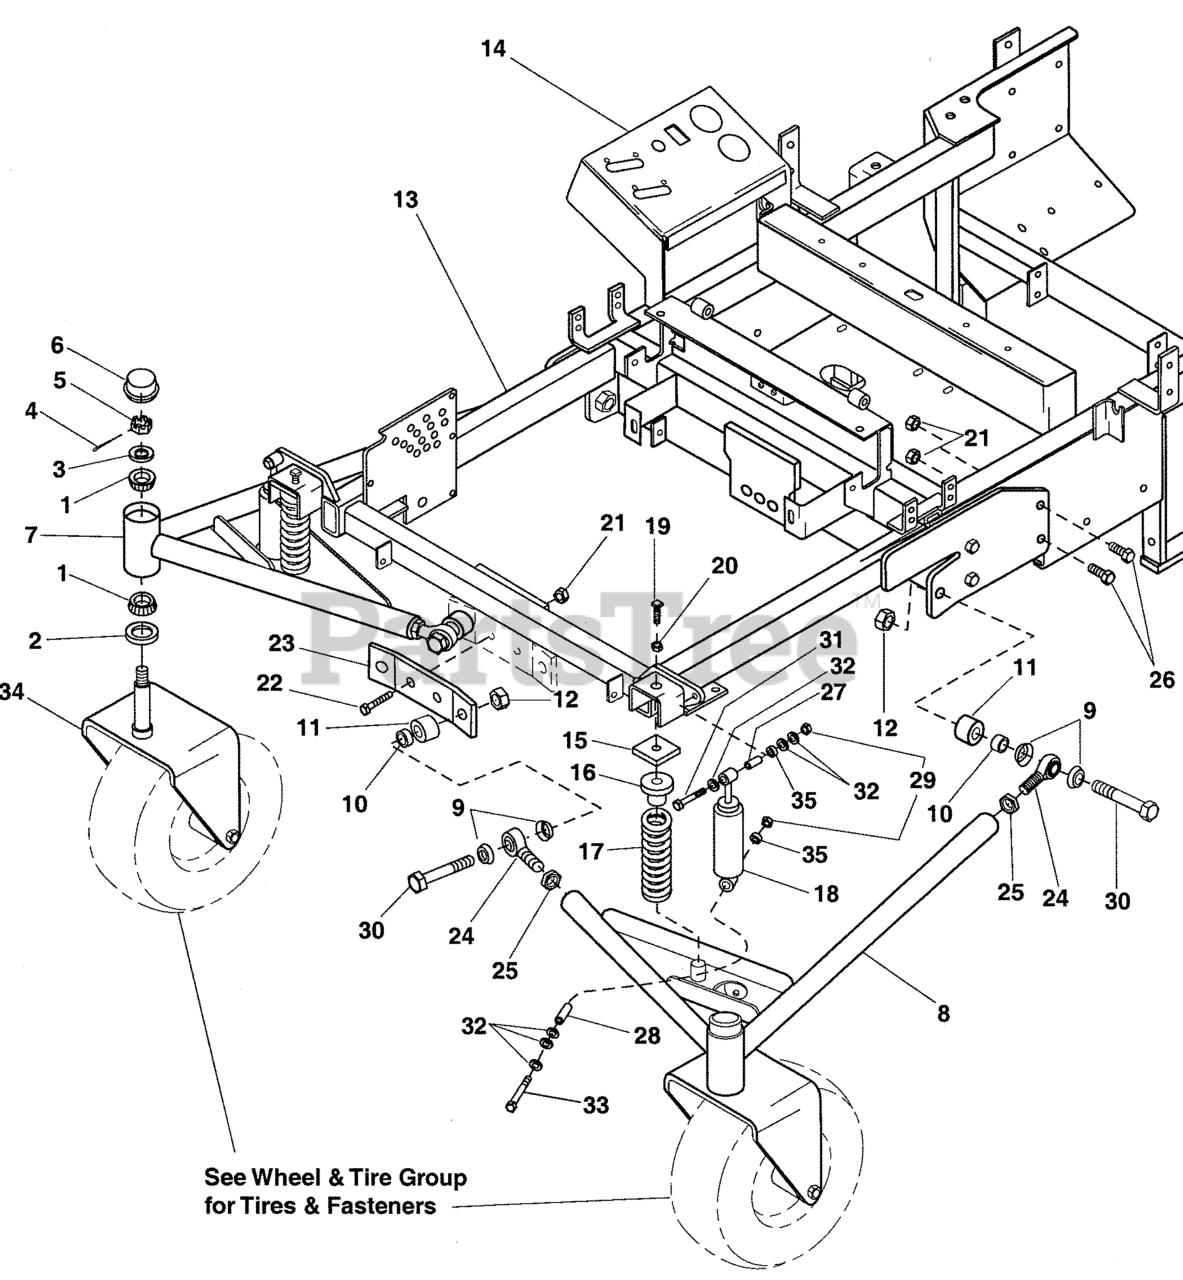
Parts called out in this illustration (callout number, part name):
1	BEARING, Tapered Roller
2	SEAL, GREASE
3	WASHER, 3/4 SAE
4	PIN, COTTER, 1/8 X 1-1/4
5	NUT, Hex, Slotted, 3/4-16
6	CAP
7	SUSPENSION ARM, Right
8	SUSPENSION ARM, Left
9	ROD END SEAL
10	SPACER, SMALL
11	SPACER, LARGE
12	NUT, Hex, Nylon Lock, 3/4-16
13	FRONT FRAME
14	MAIN FRAME
15	SPRING COMPRESSION PLATE
16	SPRING RETAINER
17	SPRING, SUSPENSION
18	SHOCK ABSORBER
19	SET SCREW, Square Hd, 1/2-13 x 3
20	NUT, Hex, Jam, 1/2-13
21	NUT, Hex, Nylon Lock, 1/2-20
22	BOLT, 1/2-20 X 1-3/4" GD8 CZ
23	SUSPENSION SUPPORT PLATE
24	BALL JOINT, 3/4-16
25	NUT, Hex, Jam, 3/4-16
26	BOLT, 1/2-20 X 1-1/4" GD5 CZ
27	MOUNT, SHOCK
28	SPACER, Lift Plate
29	NUT, Hex, Side Lock, 3/8-16
30	BOLT, 3/4-16 x 4
31	BOLT, 3/8-16 X 2-1/2" GD5 CZ
32	WASHER, 3/8 SAE
33	BOLT, 3/8-16 X 3-1/2" GD5 CZ
34	YOKE, Caster
35	SPACER, Lift Ball Joint
